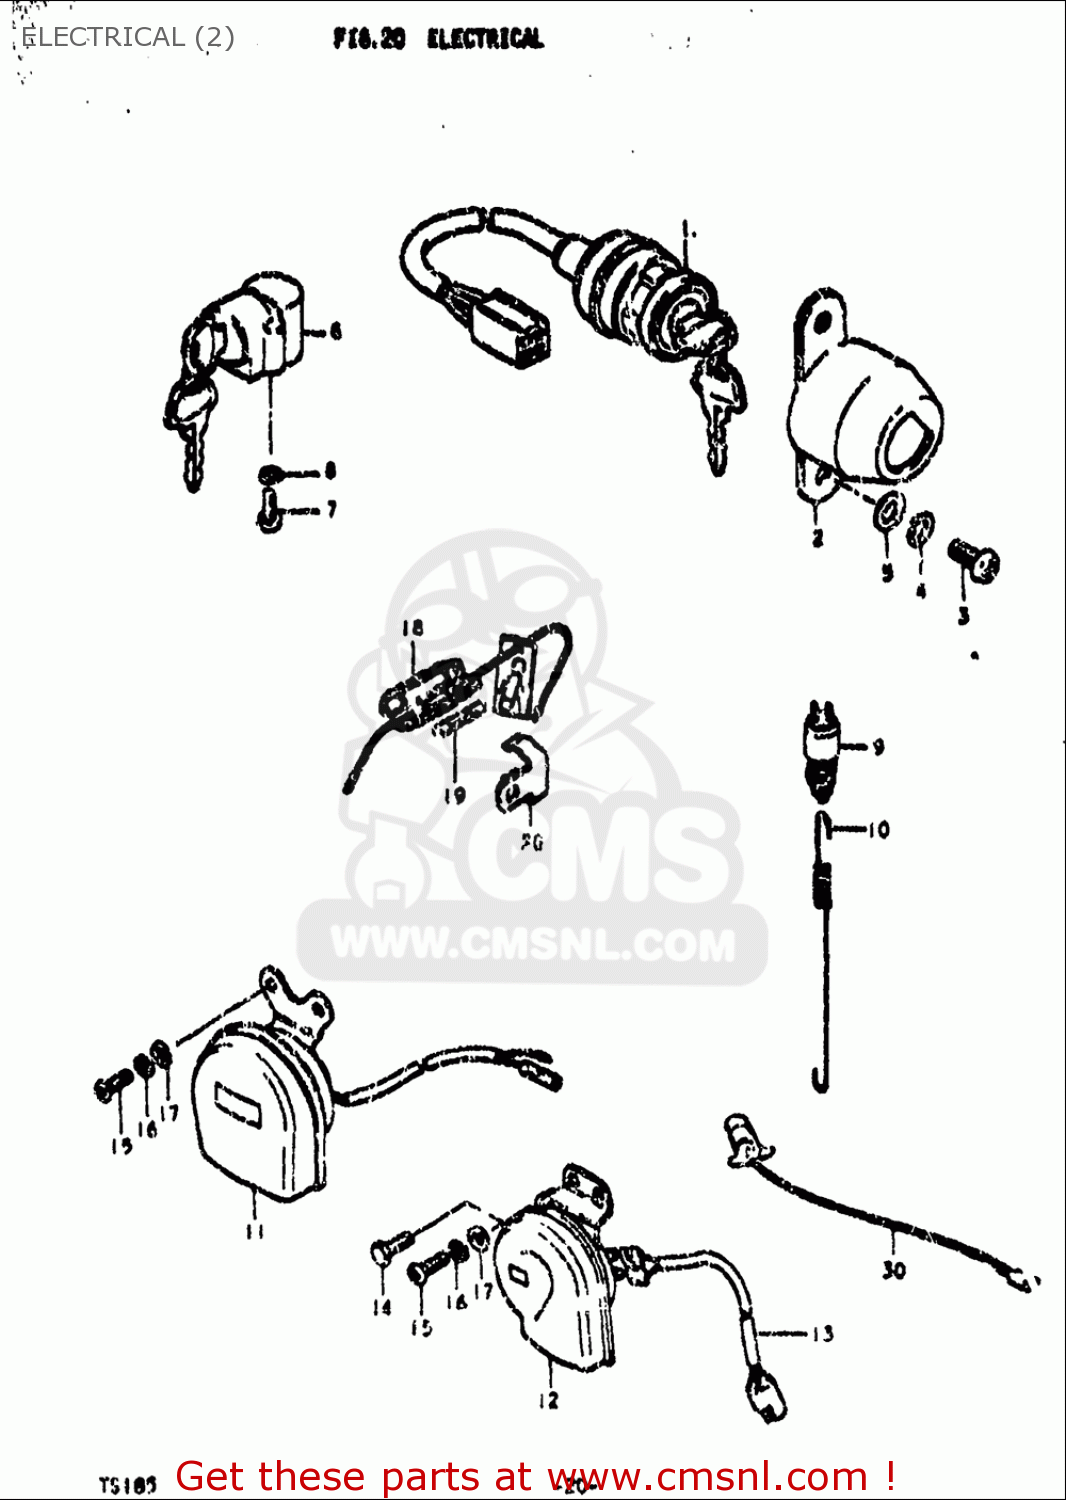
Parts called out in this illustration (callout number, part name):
3	SCREW
4	WASHER,LOCK
5	WASHER
6	LOCK ASSY,STEERING
7	SCREW
8	WASHER,LOCK
9	SWITCH ASSY,BRAKE LAMP
10	SPRING
11	HORN ASSY
12	HORN ASSY
13	WIRE,HORN LEAD
14	BOLT
15	SCREW
16	WASHER,LOCK
17	WASHER
18	CASE ASSY,FUSE
19	FUSE(15A)
